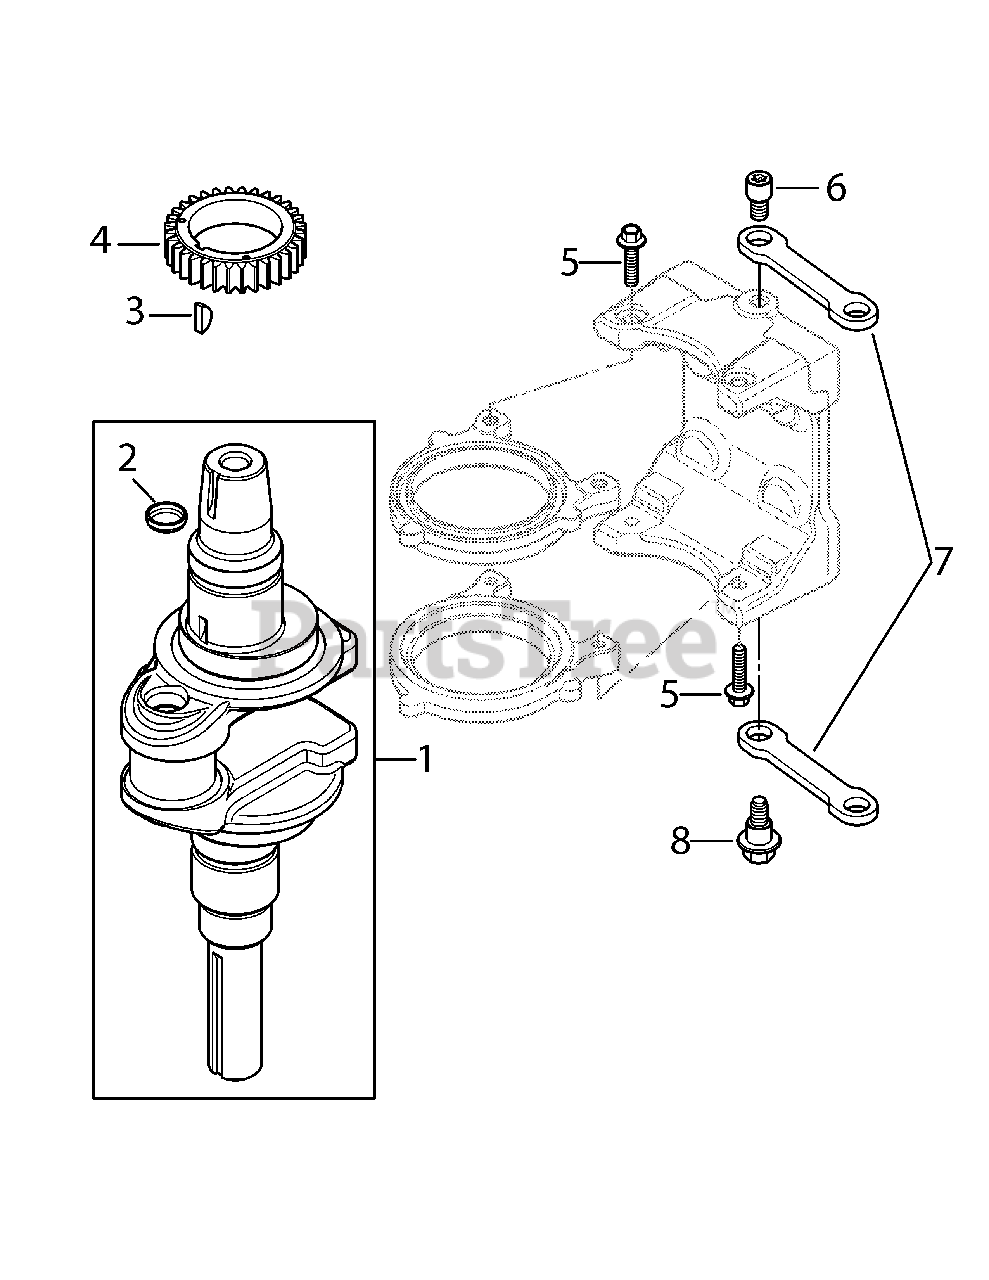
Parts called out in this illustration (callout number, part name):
1	Crankshaft Assembly Kit
3	Key, 3/16 X 5/8
4	Crankshaft Gear
5	Flange Screw, M6 X 1.0 X 25
6	Link Pivot Screw
7	Balance Weight Linkage
8	Shoulder Screw
